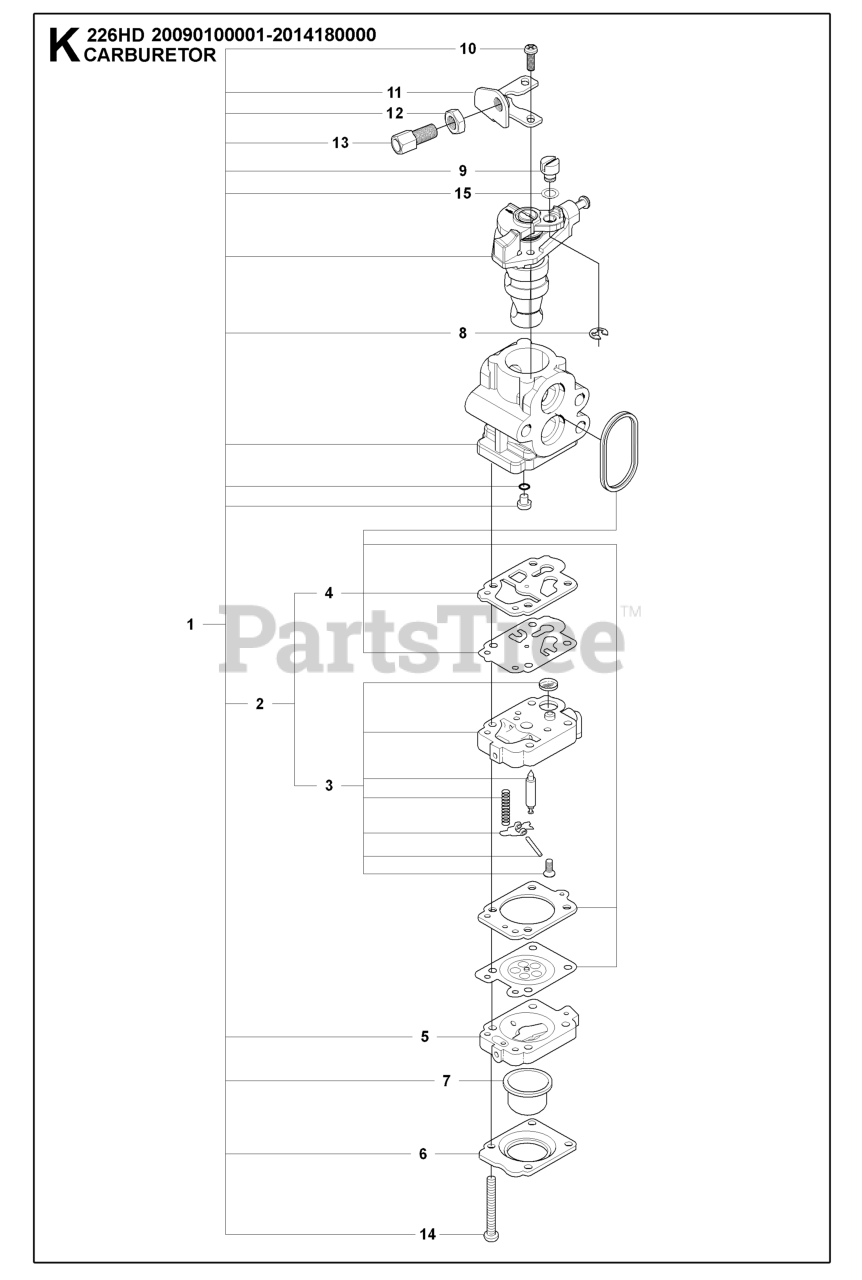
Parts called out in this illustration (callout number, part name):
1	CARBURETOR ASSY
2	REBUILD KIT
3	CARBURETOR BODY
4	GASKET KIT
12	NUT
13	ADJUSTER
